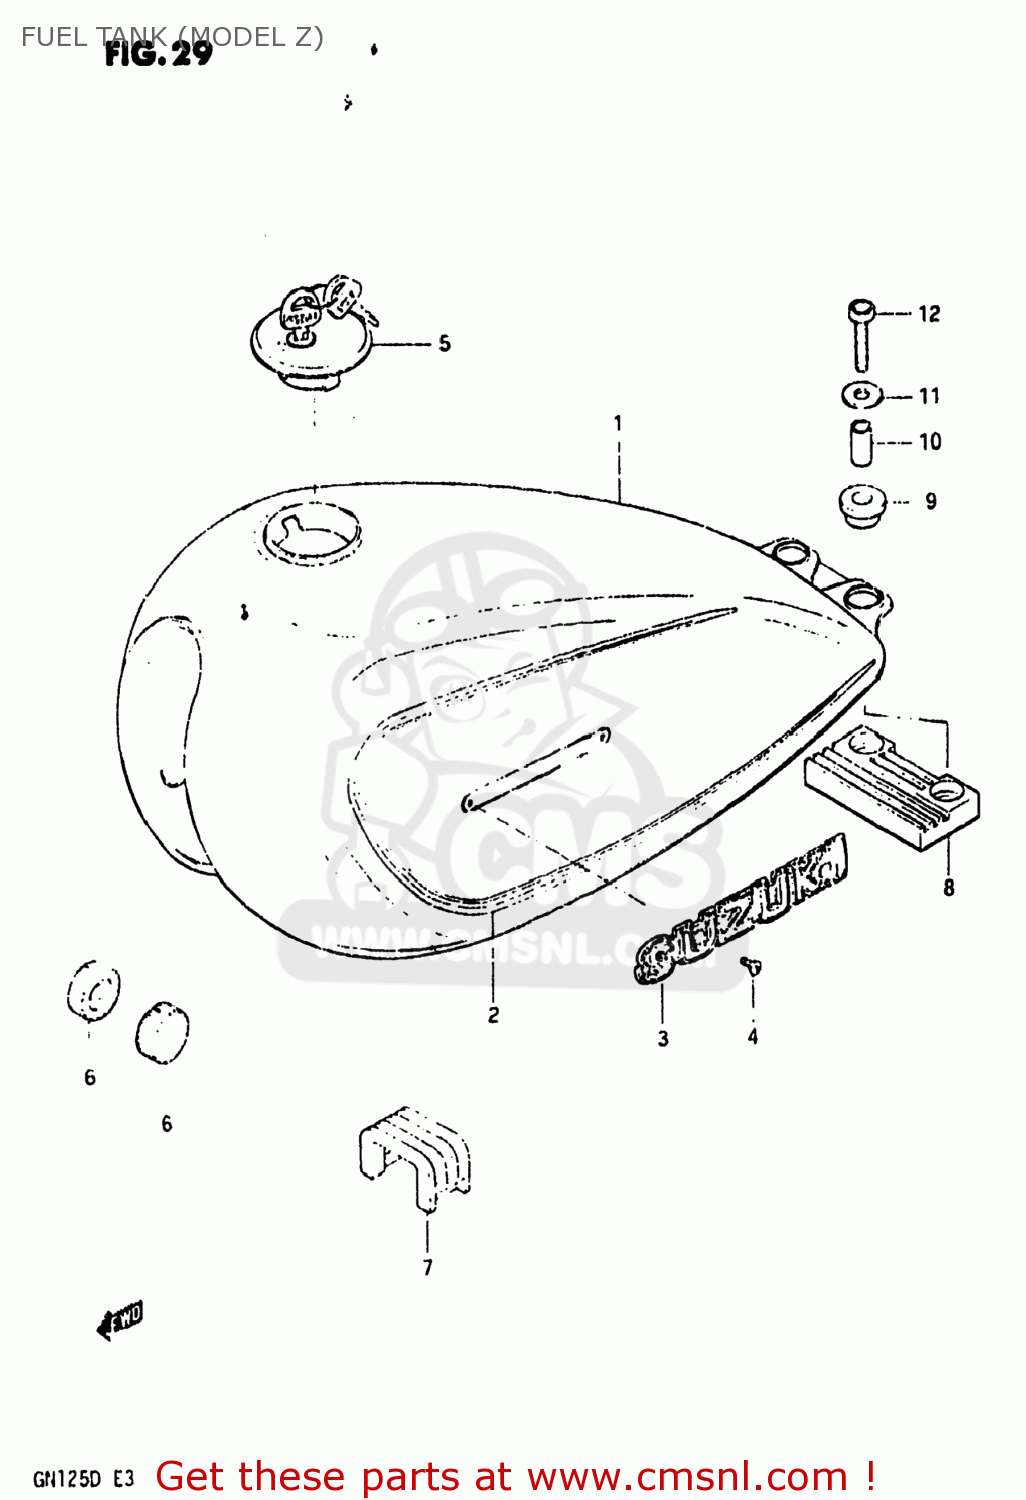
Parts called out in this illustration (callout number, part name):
1	TANK ASSEMBLY,FUEL
2	TAPE SET,FUEL TANK
3	EMBLEM,FUEL TANK
4	SCREW 3X6
5	CAP SET,FUEL TANK
6	CUSHION
7	CUSHION,FUEL TANK UPR FR
8	CUSHION,TANK RR NO.1
9	CUSHION
10	SPACER(6.5X10.5X22.5)
11	WASHER(6,5X22X1.6)
12	BOLT(6X35)
